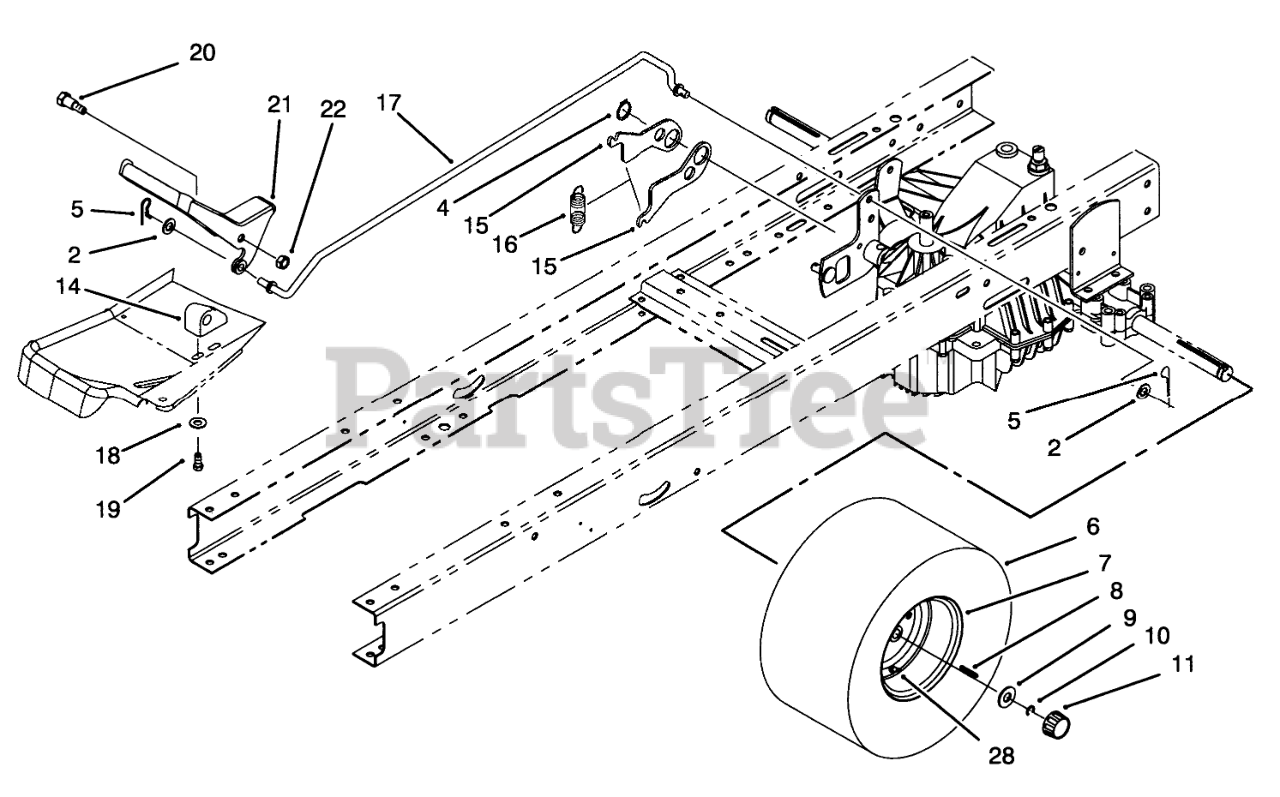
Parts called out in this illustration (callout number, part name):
2	WASHER-PLAIN
4	RING-SNAP
5	PIN-COTTER
6	TIRE 18 X 9.50 X 8
8	KEY-SQUARE
9	WASHER-PLAIN
10	E-RING
11	CAP-HUB
14	BLOCK-PIVOT
15	NEUTRAL RETURN LEVER
16	SPRING-EXTENSION
17	SPEED CONTROL ROD
18	WASHER-FLAT
19	SCREW-PLASTITE
20	SCREW-SHOULDER, HH
21	Pedal-Speed Control
22	NUT-LOCK, NI
28	STEM-VALVE
